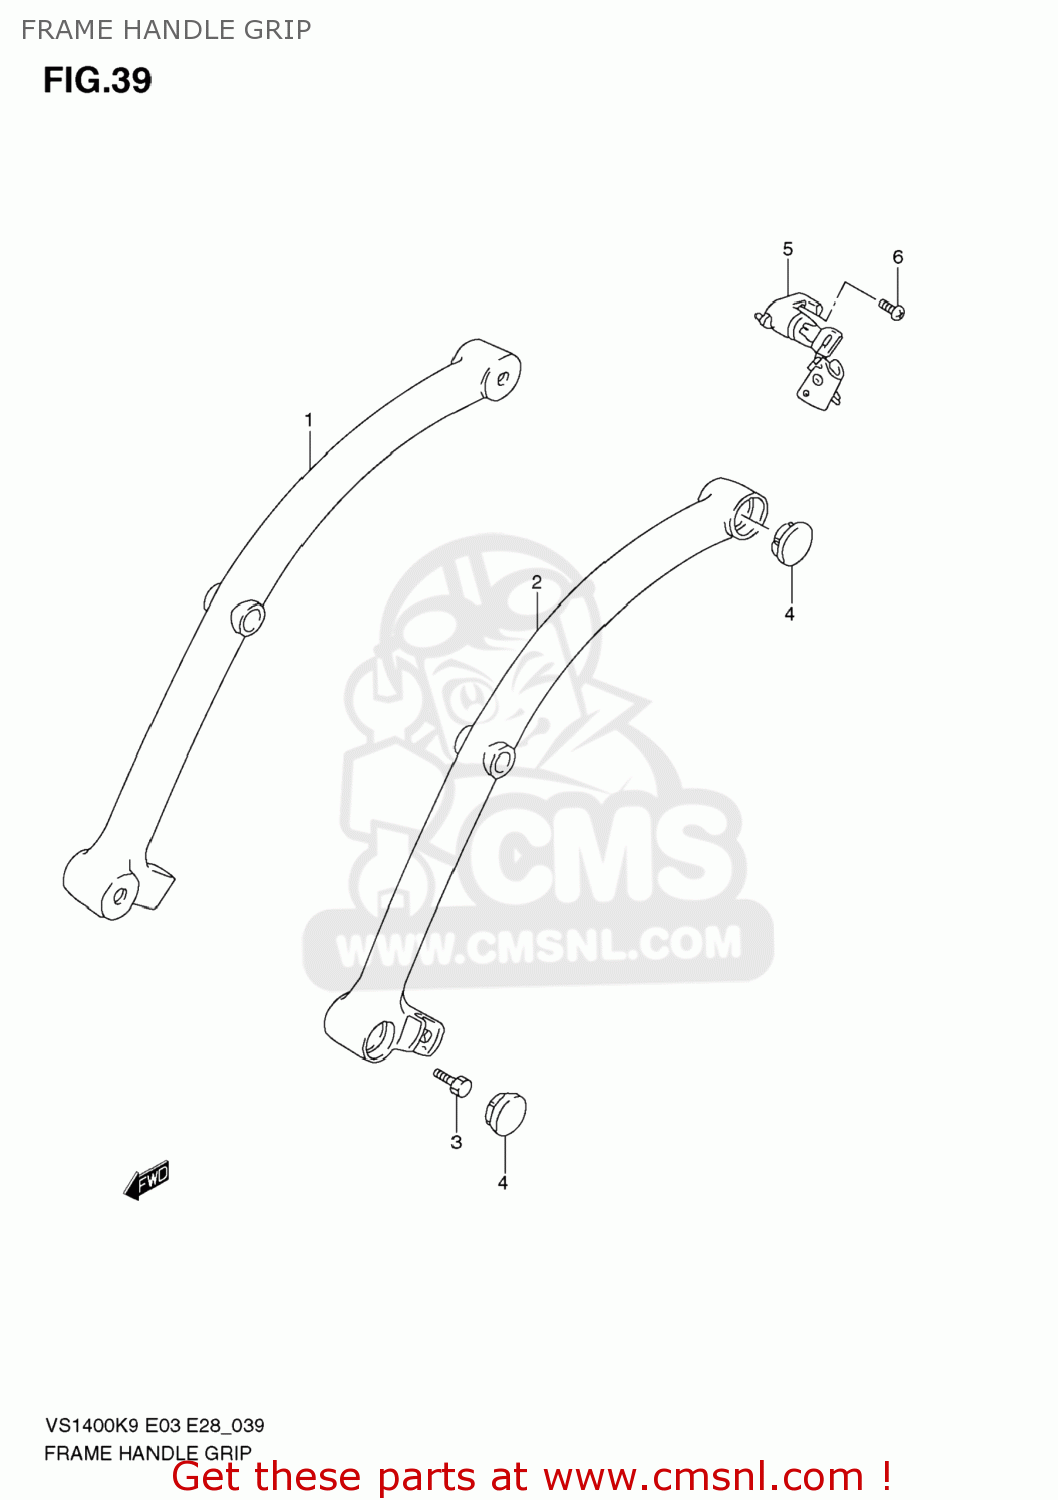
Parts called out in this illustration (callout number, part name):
1	GRIP,FRAME HANDLE,R
2	GRIP,FRAME HANDLE,L
3	BOLT
4	CAP,PIPE CO-RIDER GRIP
5	LOCK SET,HELMET
6	SCREW
